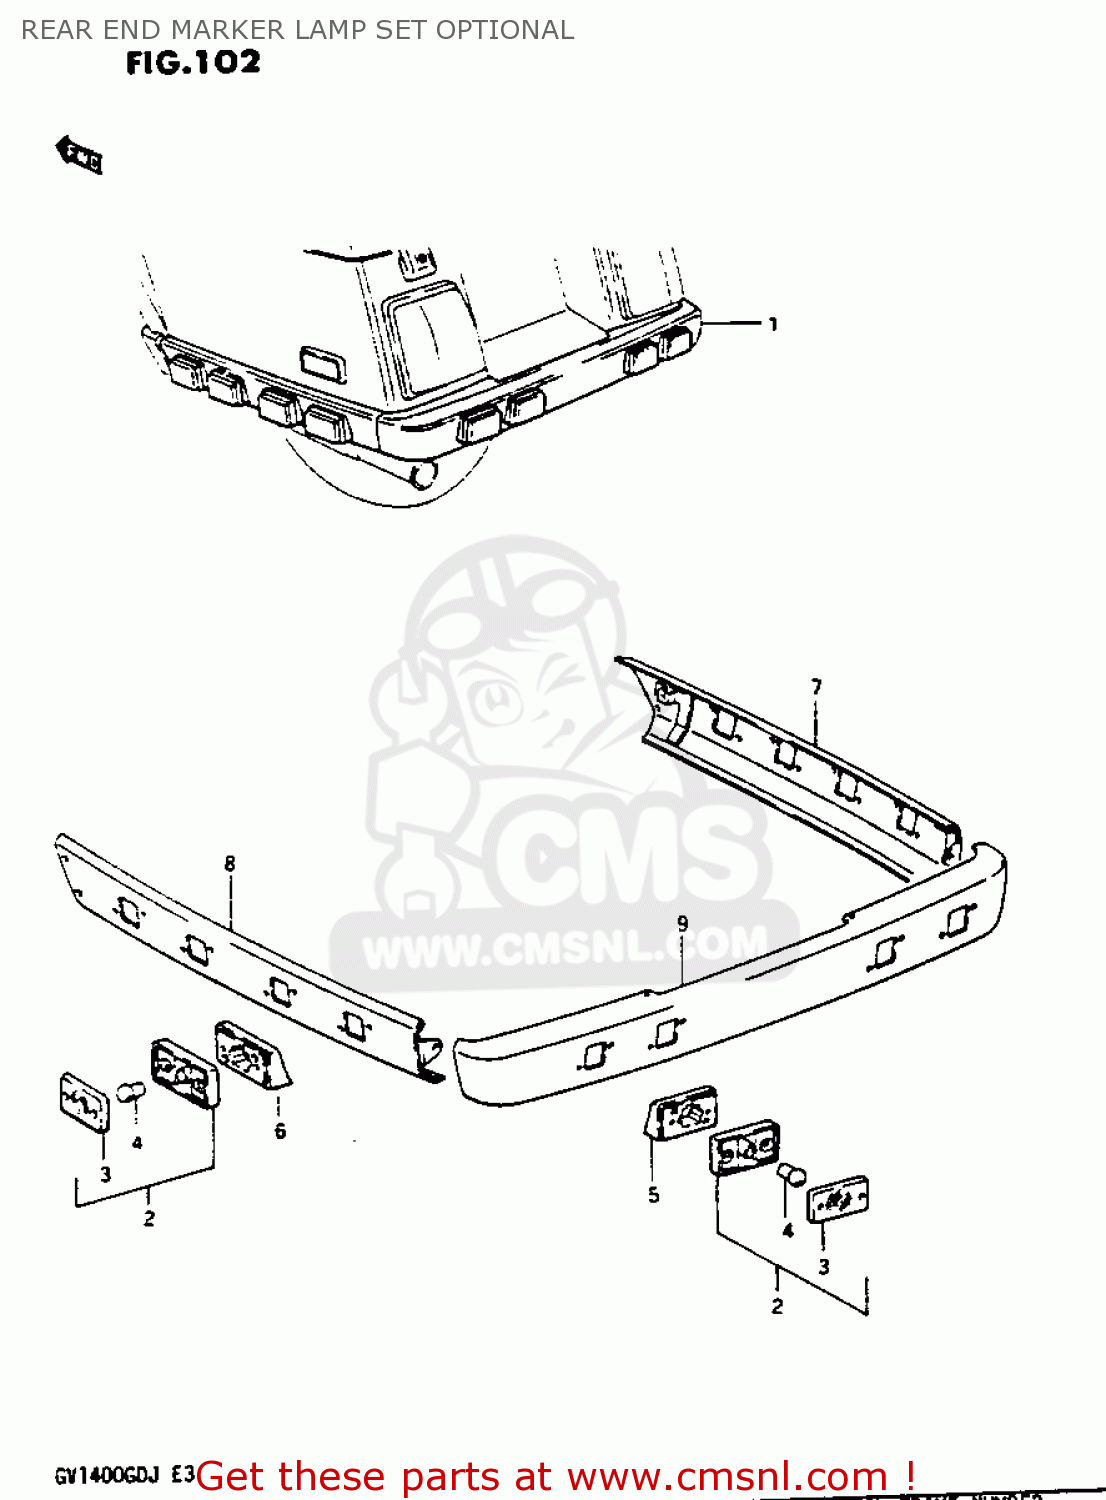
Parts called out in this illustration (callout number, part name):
1	REAR END,MARKER LAMP S
2	TRAVEL TRUNK,MARKER LAMP
3	LENS
4	BULB 12V 3W
5	BASE,MARKER LAMP MOUNT
6	BASE,MARKER LAMP MOUNT
7	REAR END,RIGHT COVER
8	REAR END,LEFT COVER
9	TRIM,SIDE BAG CARRIER
